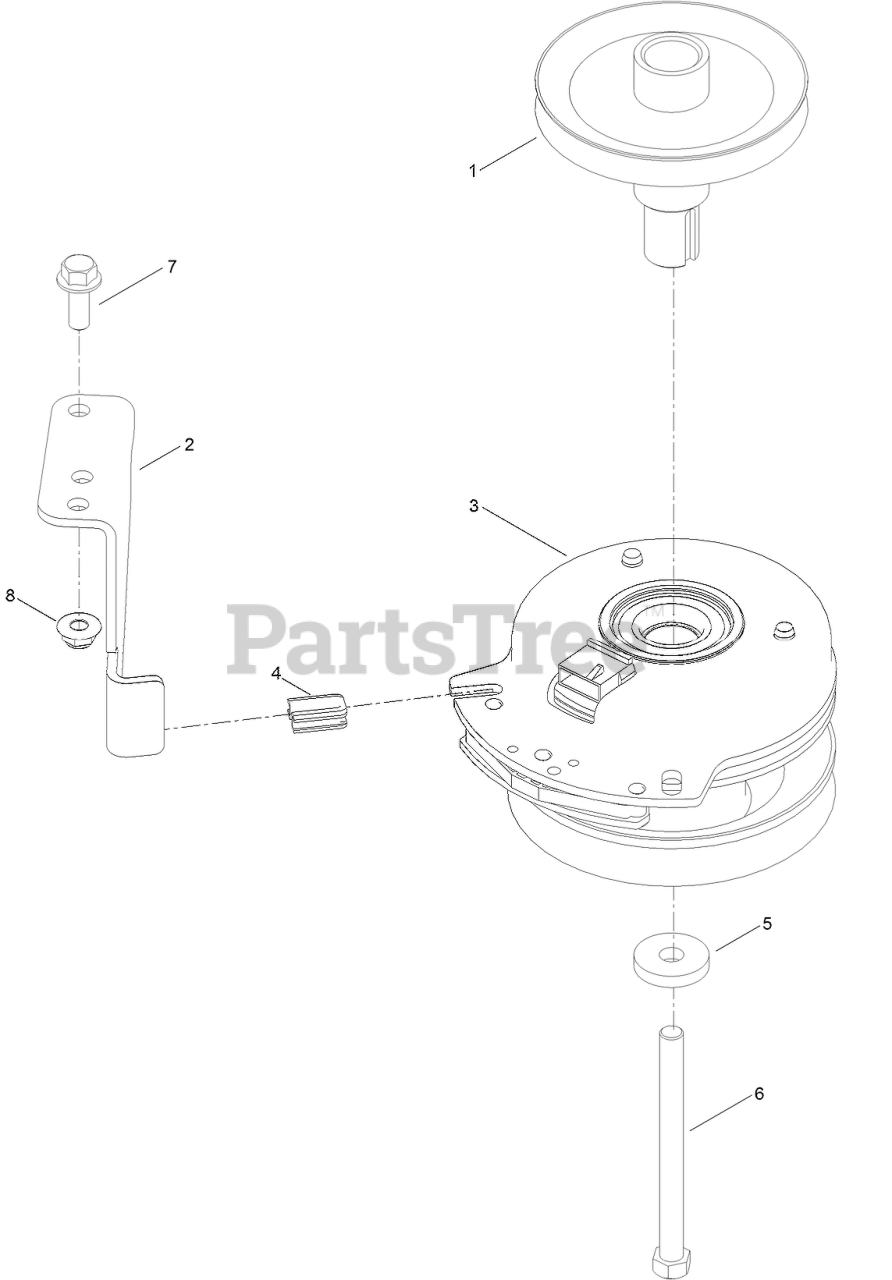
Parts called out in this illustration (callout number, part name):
1	PULLEY-ENGINE
2	STOP-CLUTCH (WIDE)
3	CLUTCH-PTO
4	ISOLATOR-CLUTCH
5	WASHER
6	SCREW-HH
7	SCREW-HHF
8	NUT-HF, NI
